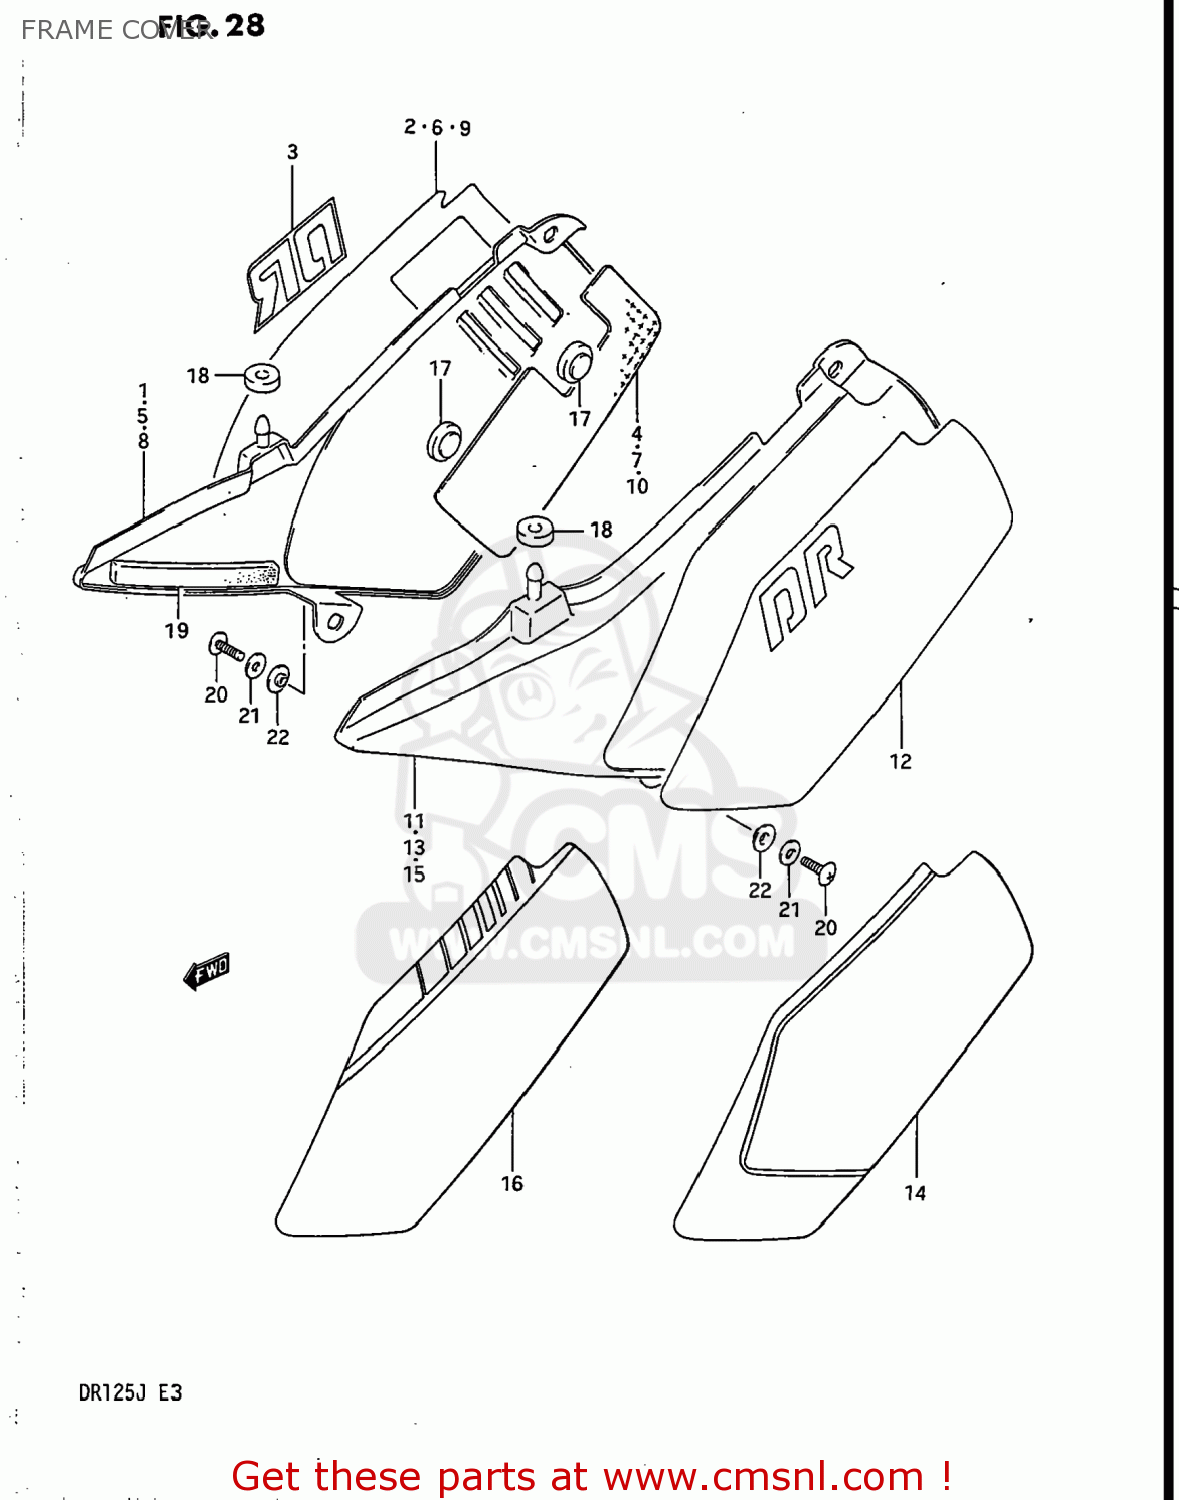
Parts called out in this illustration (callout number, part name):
1	COVER,FRAME,RIGHT
2	TAPE SET,FRAME COVER,RIGHT
3	EMBLEM,RIGHT
4	SHIELD,FRAME COVER,RIGHT
5	COVER,FRAME,RIGHT
6	TAPE SET,FRAME COVER,RIGHT
7	SHIELD,FRAME COVER,RIGHT
8	COVER COMP,FRAME,RIGHT
9	TAPE,FRAME COVER,RIGHT
10	SHIELD,FRAME COVER,RIGHT
11	COVER,FRAME,LEFT
12	TAPE SET,FRAME COVER,LEFT
13	COVER,FRAME,LEFT
14	TAPE SET,FRAME COVER,LEFT
15	COVER COMP,FRAME,LEFT
16	TAPE,FRAME COVER,LEFT
17	CUSHION
18	CUSHION,SIDE COVER BOSS
19	CUSHION,FRAME COVER
20	SCREW
21	WASHER (6.5X18X1.6)
22	WASHER
